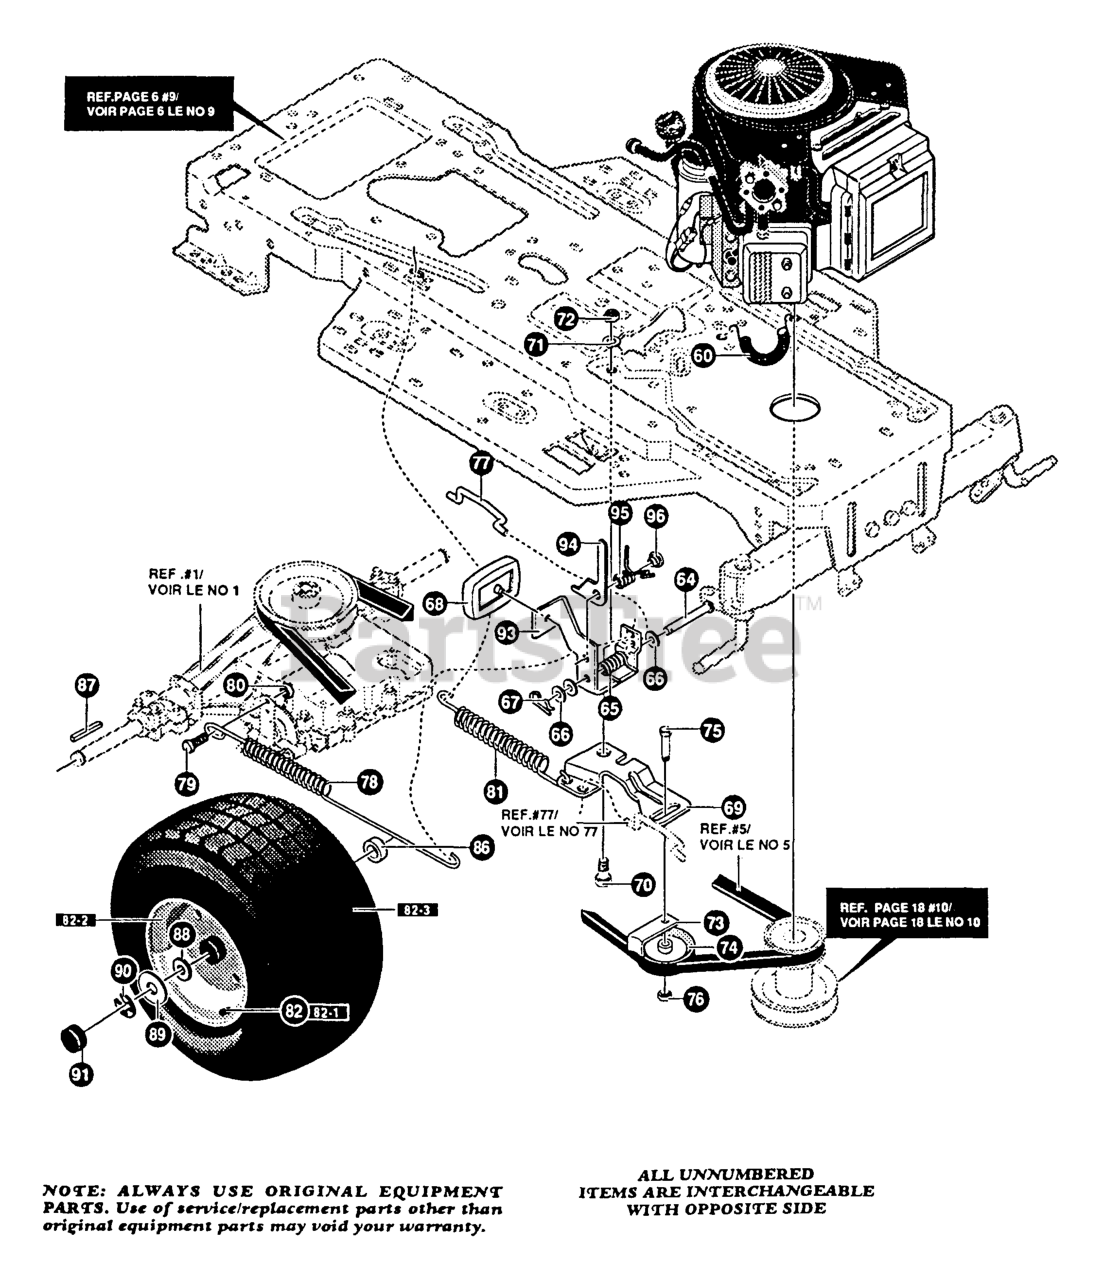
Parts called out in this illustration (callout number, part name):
60	SPRING
64	PIN, CLEVIS
65	SPRING, BRAKE PEDAL
66	WASHER
67	PIN, HAIR
68	PAD, CLUTCH BRAKE
69	ARM, IDLER TRAC
73	RETAINER, BELT
74	PULLEY, IDLER
76	NUT
77	ROD, CLUTCH
78	SPRING, BRAKE
81	SPRING, CLUTCH
82	TIRE & RIM 20"
82-1	VALVE STEM
82-2	RIM, WHEEL
82-3	TIRE, 20"
86	SPACER
87	KEY, SQUARE
88	WASHER
90	RING, RETEX
91	HUB CAP
93	PEDA, CLUTCH/BRAKE
94	LEVER, PARK BRAKE
95	SPRING, BRAKE
96	RIVET
